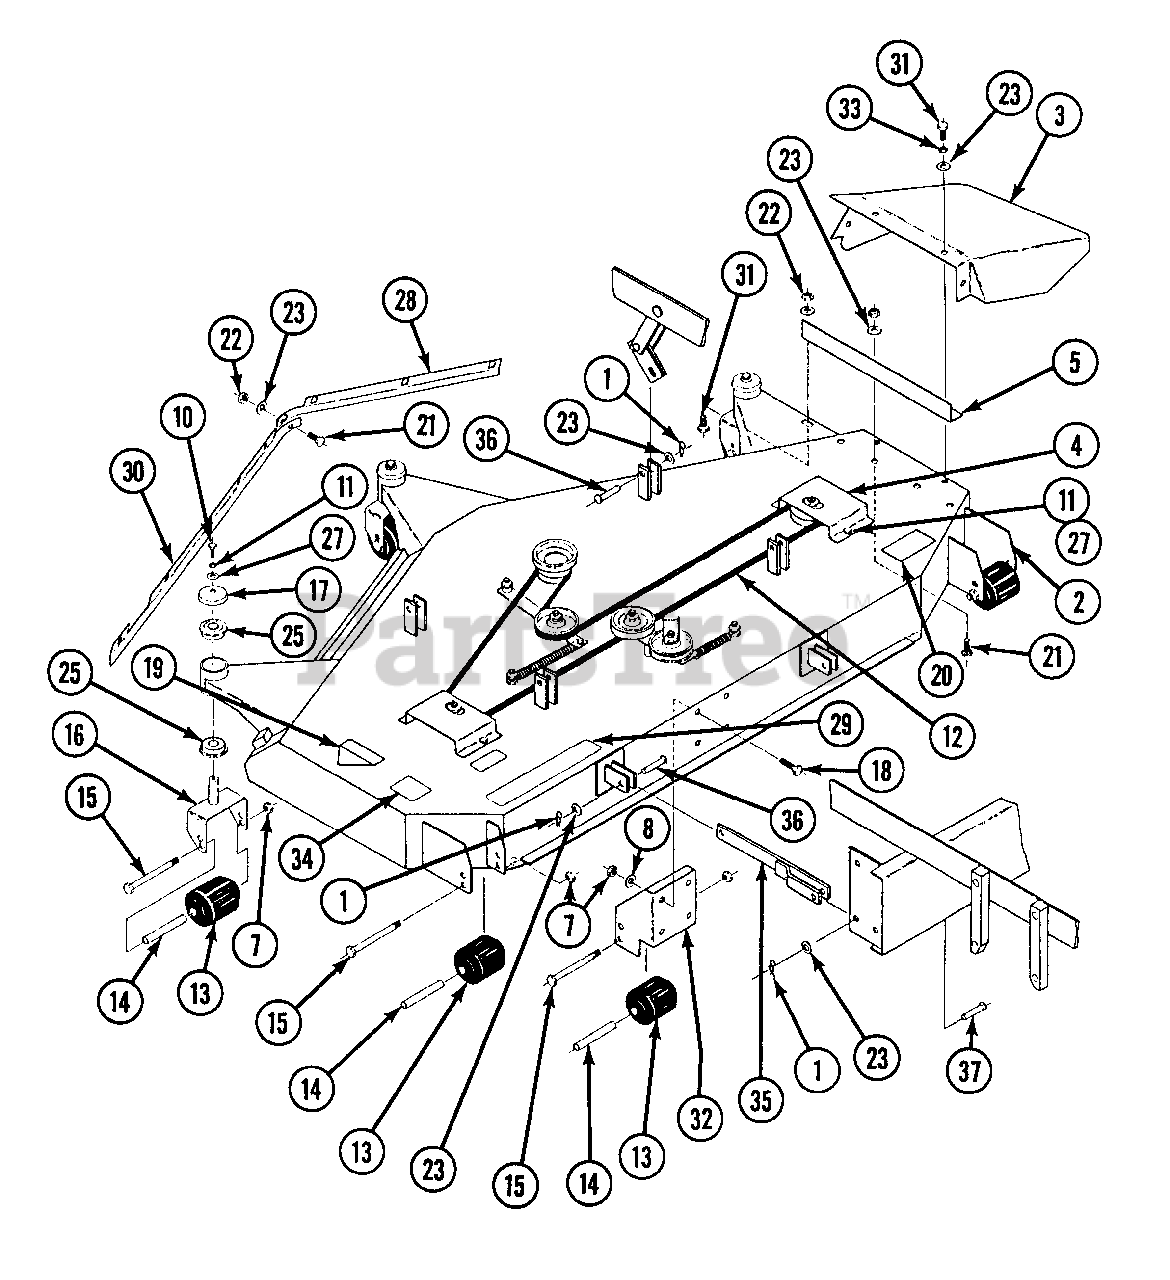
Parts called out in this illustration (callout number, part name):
1	COTTER, RUE RING: 5/16 - 3/8
2	60" DECK WELDMENT
3	60" DECK CHUTE ASSEMBLY
4	PULLEY COVER
5	OUTLET STIFFENER
7	LOCKNUT, NYLOCK: 3/8-16
8	FLAT WASHER, STD: 3/8
10	CAPSCREW, HX HD: 1/4-20 X 3/4 GR 5
11	LOCKWASHER, SPLT SPRNG: 1/4
12	DECK BELT: A-112
13	ROLLER, LOW DENSITY POLYETHYLENE
14	BUSHING, ROLLER
15	CAPSCREW, HX HD: 3/8-16 X 6 GR 5
16	YOKE WLDT, SWIVEL
17	BEARING CAP
18	CAPSCREW, HX HD:3/8-16 X 7/8 GR 5
19	DECAL, BLOODY STUMP
20	DECAL, CHUTE (SAFETY)
21	BOLT, CARRIAGE: 5/16 X 3/4
22	LOCKNUT, NYLOCK: 5/16-18
23	FLAT WASHER, STD: 5/16
25	BEARING: 1"ID X 2" OD
27	FLAT WASHER, 1/4
28	LIP BAFFLE, RH
29	DECAL, "ZU6003M"
30	LIP BAFFLE, LH
31	CAPSCREW, HX HD: 5/16-18 X 3/4 GR 5
32	REAR ANTI-SCALP BRACKET
33	LOCKWASHER, SPLT SPRNG: 5/16
34	DECAL, "GREASE SPINDLES.."
35	DRAG BAR WELDMENT
36	PIN, CLEVIS: 3/8 X 2
37	PIN, CLEVIS: 3/8 X 1-5/16
